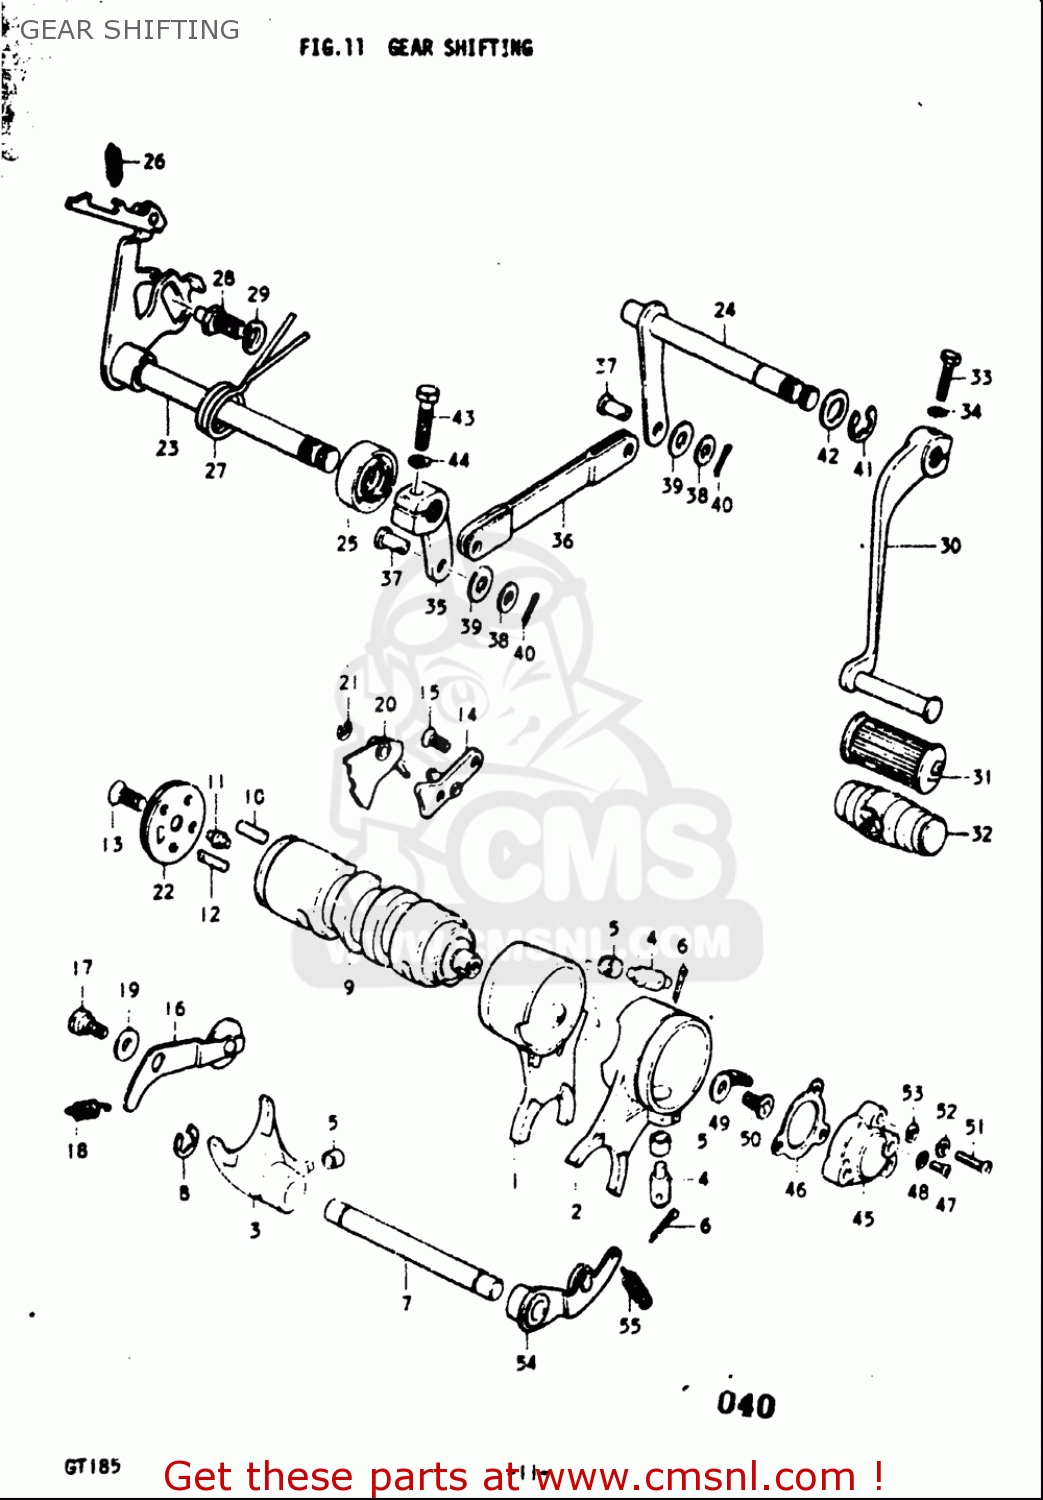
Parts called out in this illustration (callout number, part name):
1	FORK,GEAR SHIFT NO.1
2	FORK,GEAR SHIFT NO.2
4	PIN
5	SPACER(6X9.8X6)
6	PIN
8	E RING
10	PIN(4X20)
11	PIN
12	PIN
13	SCREW
15	SCREW
17	BOLT(6X16.1)
18	SPRING
19	WASHER(6.5X16X2.3)
21	E RING
25	SEAL,OIL (12X22X9)
26	SPRING
29	WASHER,LOCK
30	LEVER ASSEMBLY,GEAR SHIFTING
31	RUBBER,GEAR SHIFT PEDAL
32	RUBBER,GEAR SHIFT PEDAL
33	BOLT
34	WASHER,LOCK
36	LEVER,GEAR SHIFT LINK
37	PIN
38	SHIM(8.8X14X1)
40	PIN 20X10
41	E RING
42	WASHER(12.5X20X1)
43	BOLT
44	WASHER,LOCK
45	BODY,CHANGE SWITCH
46	GASKET,GEAR SHIFT SWITCH (NAS)
47	SCREW
48	WASHER
49	CONTACT,GEAR SHIFT SWITCH
50	SCREW
51	SCREW
52	WASHER,LOCK
53	WASHER
